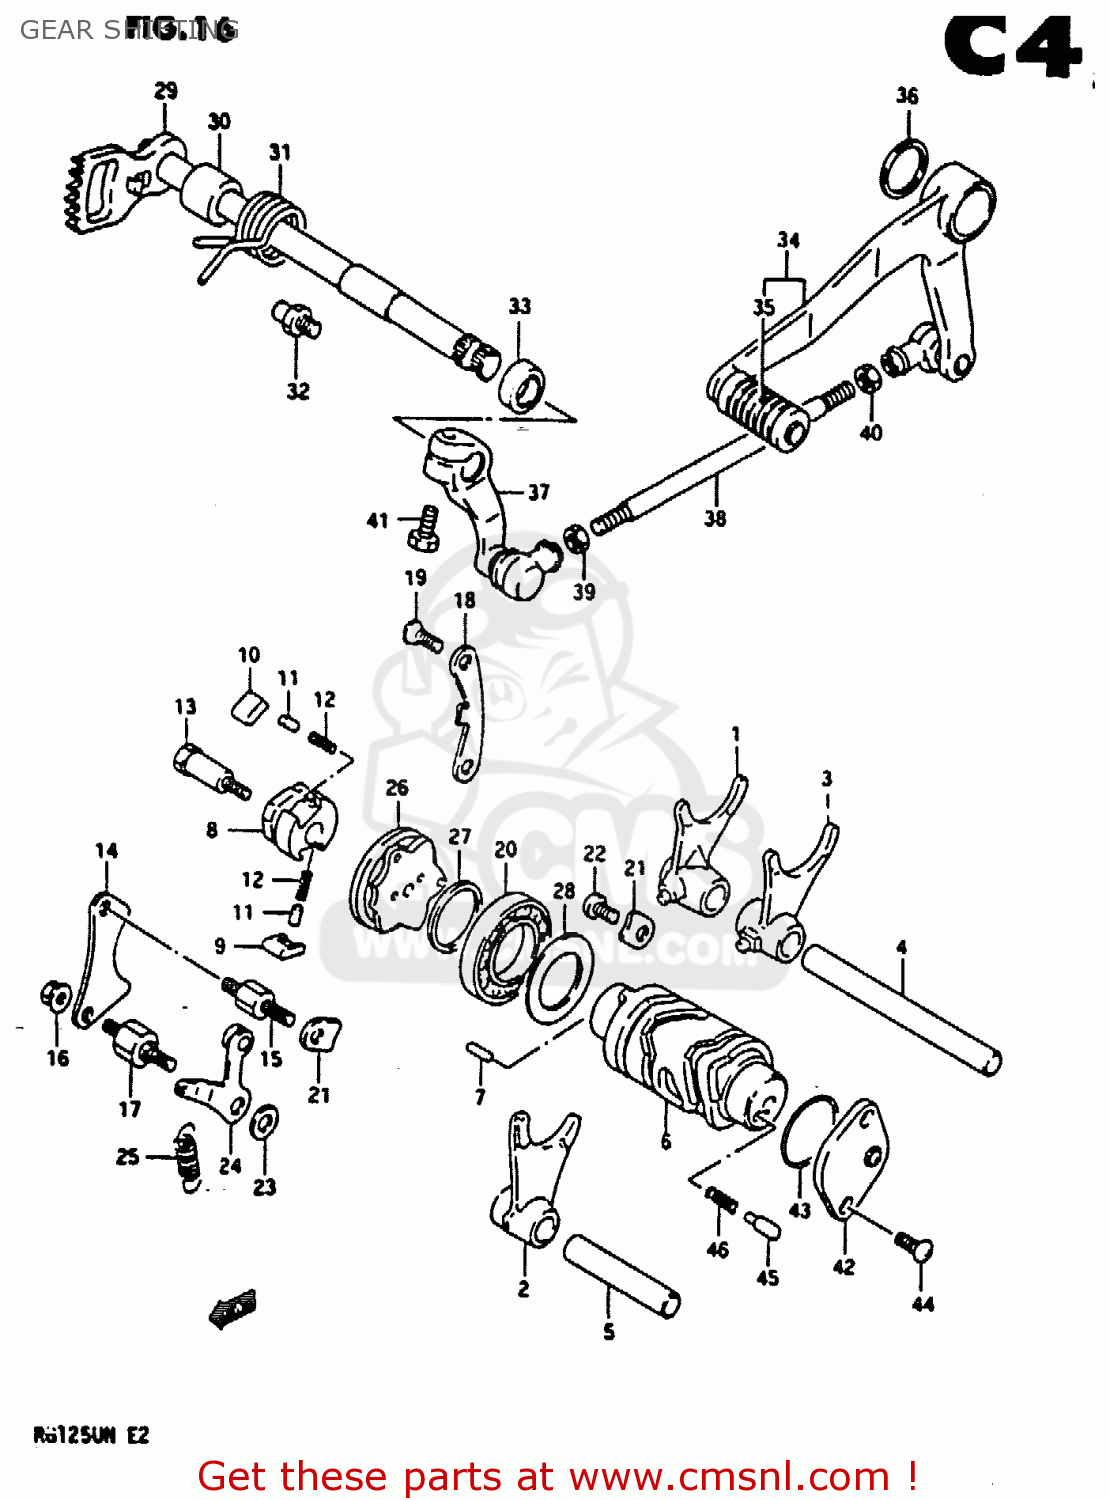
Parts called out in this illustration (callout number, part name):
1	FORK,GEAR SHIFT NO.1
2	FORK,GEAR SHIFT NO.2
3	FORK, NO. 3
4	SHAFT,GEAR SHIFT FORK(L:109)
5	SHAFT,GEAR SHIFT FORK
6	CAM
7	PIN
8	GEAR,GEARSHIFT CAM DRIVE
9	PAWL,GEAR SHIFT NO.1
10	PAWL,GEAR SHIFT NO.2
11	PIN(5X8)
12	SPRING
13	PIN,SHIFT CAM DRIVEN GEAR
14	LIFTER,GEAR SHIFT POLE
15	BOSS,SHIFT PAWL LIFTER
16	NUT
17	SUPPORT,CAM STOPPER ARM
18	GUIDE,GEAR SHIFT CAM
19	SCREW
20	BEARING
21	RETAINER,GEAR SHIFT CAM BRG
22	SCREW 6X12
23	WASHER
24	STOPPER, CAM
25	SPRING
26	PLATE,GEAR SHIFT CAM
27	WASHER(25X32X3)
28	SEAL,SHIFT CAM OIL
29	SHAFT,GEAR SHIFT
30	SPACER(12X20X15.3)
31	SPRING
32	STOPPER,GEAR SHIFT ARM
33	OIL SEAL
34	LEVER ASSY,GEAR SHIFT
35	RUBBER,GEAR SHIFT PEDAL
36	WASHER
37	ARM,GEAR SHIFT LINK
38	ROD, GEAR SHIFT LINK (L:180)
39	NUT
40	NUT
41	BOLT
42	BODY,GEAR SHIFT SWITCH
43	O-RING (D:2.4 ID:26.2)
44	SCREW
45	PIN(5X15.5)
46	SPRING
